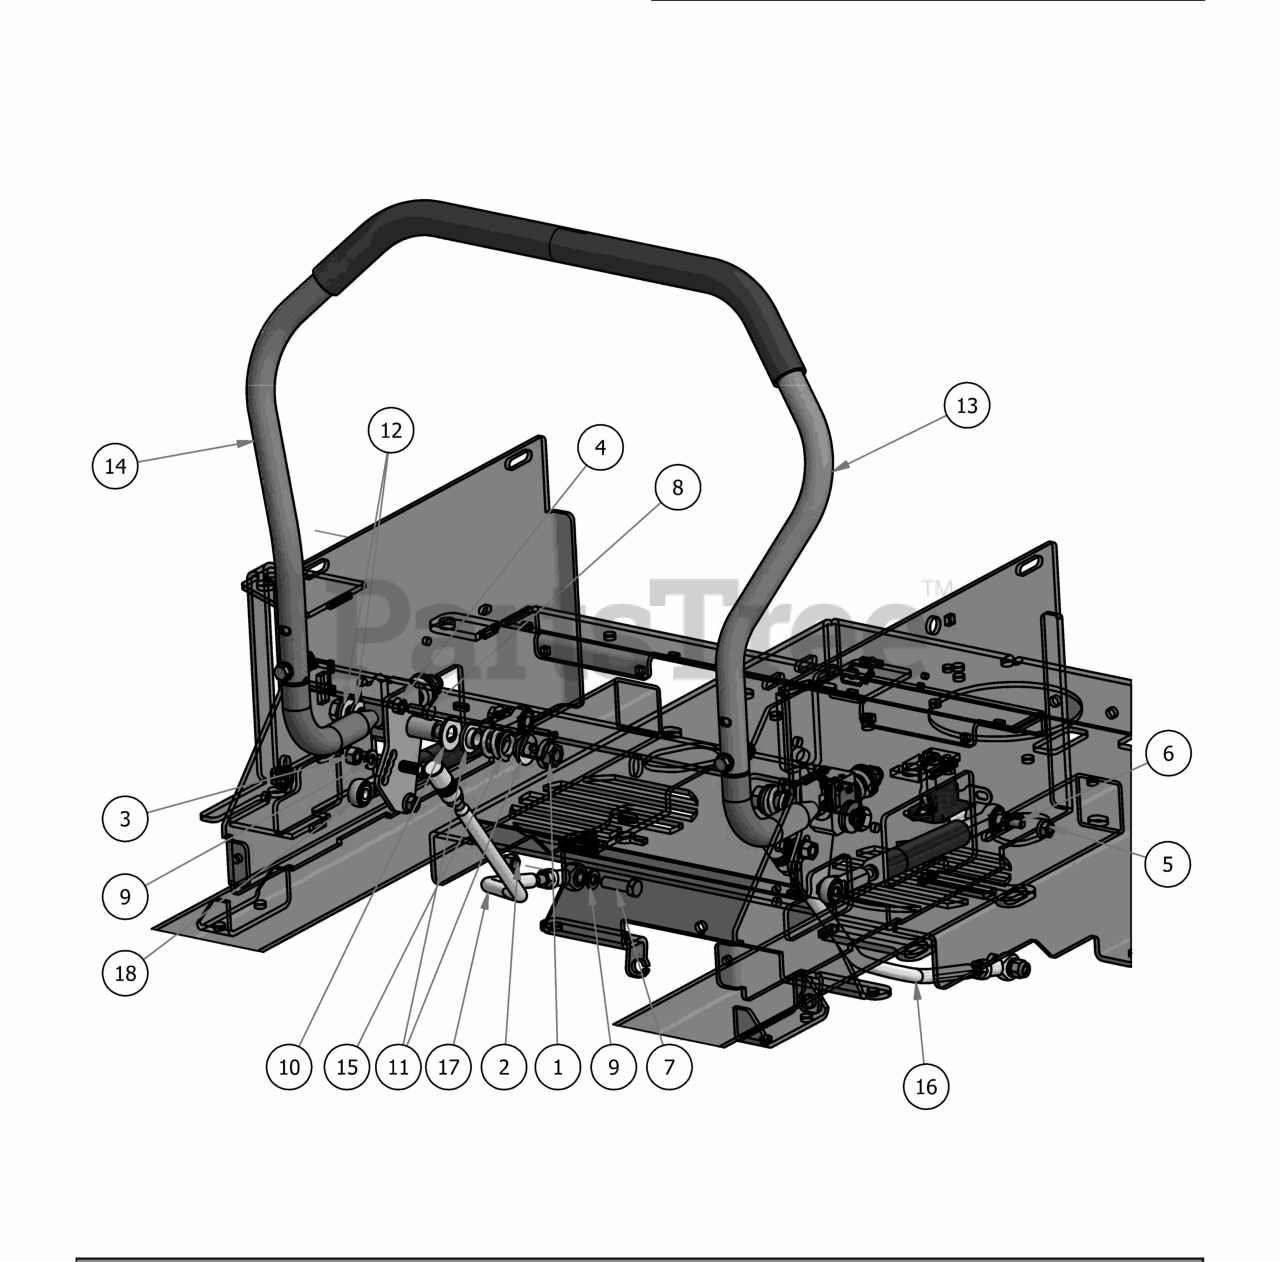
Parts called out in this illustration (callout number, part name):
1	1/2-13 Mechanical Lock Nut
2	3/8 Nylock Nut
3	3/8" Fine Threaded Jam Nut
5	5/16" Flange Nut
6	10mm Damper Ball Stud-Steering
7	3/8" x 1 1/4" Hex Bolt
8	5/16" x 3/4" Hex Bolt
9	3/8" Lock Washer
10	1/2" Washer (Grade 8)
11	.515 ID Nylon Shoulder Washer
12	.505 Nylon Spacer
13	ZT Steering Arm Assembly, Left Hand
14	ZT Steering Arm Assembly-Right Hand
15	Drive Lever Spring
16	Push Rod-Right
17	Push Rod-Left
18	Steering Damper
